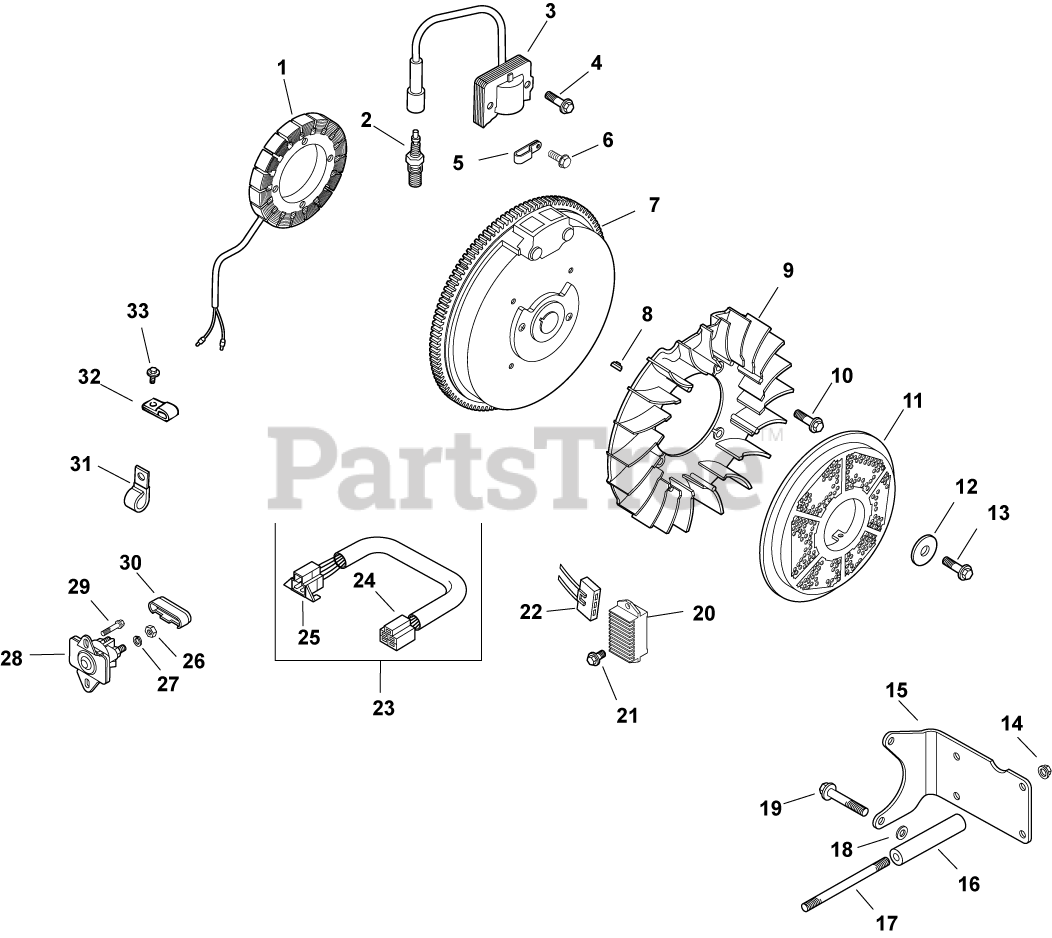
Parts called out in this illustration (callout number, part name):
1	KIT, 15 / 20 AMP STATOR
2	PLUG, SPARK (STD)
3	MODULE, IGNITION
4	SCREW, FLG THD FRM M5X.8X20-(#25086399S)
6	SCREW, FLG THD FRM M5X.8X10
7	FLYWHEEL - USE 12 025 16-S
8	KEY, 3/16" X 5/8"
9	FAN - DISCONTINUED
10	BOLT, SHOULDER
11	SCREEN, GRASS
12	WASHER, FLAT 13/32"
13	SCREW, FLG M10X1.5X45 - (#25086361S)
14	NUT, FLG M8X1.25
15	BRACKET, FUEL TANK
17	STUD, M8X1.25X133-USE 25 755 54-S
18	WASHER, FLAT 11/32"
19	SCREW, FLG M8X1.25X45
20	REG/RECT-15 AMP (KM)-USE 41 403 10-S
21	SCREW, FLG M6X1.0X16
22	CONNECTOR, BODY (KM)-USE 25 155 41-S
23	CONNECTOR ASSEMBLY
24	CONNECTOR
25	CONNECTOR
26	NUT, JAM 1/4-20 GRADE 2
27	WASHER, INT TOOTH LOCK 1/4"
28	SOLENOID - WATERPROOF (KM)-USE 25 435 08
29	SCREW,FLG THD FRM M6X1.0X16-(#25086397S)
30	CAP, SOLENOID - DISCONTINUED
31	CLIP, CABLE
32	CLIP, TUBE & WIRING (KM)
33	SCREW, M5X0.8X25 - (#25086402S)
